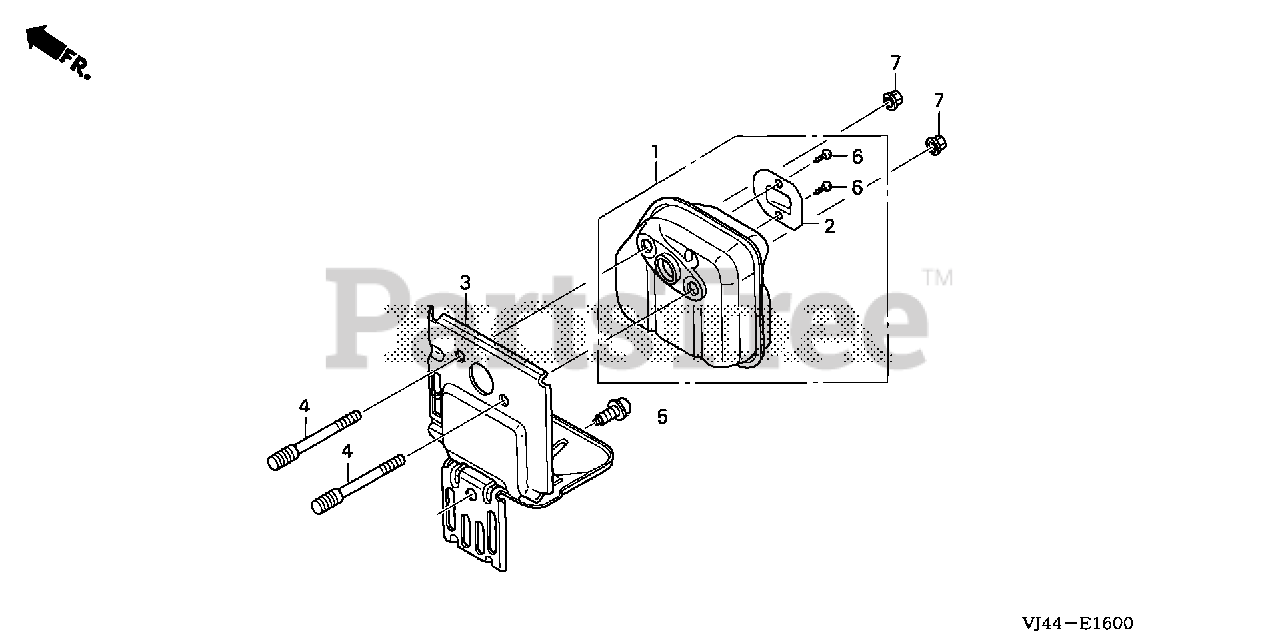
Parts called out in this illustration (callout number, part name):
2	ARRESTER, SPARK
3	GUIDE, AIR EX.
4	BOLT, STUD (5X52)
5	BOLT, SOCKET (5X10) (CT)
6	SCREW, TAPPING (4X6)
7	NUT, SELF-LOCK (5MM)
